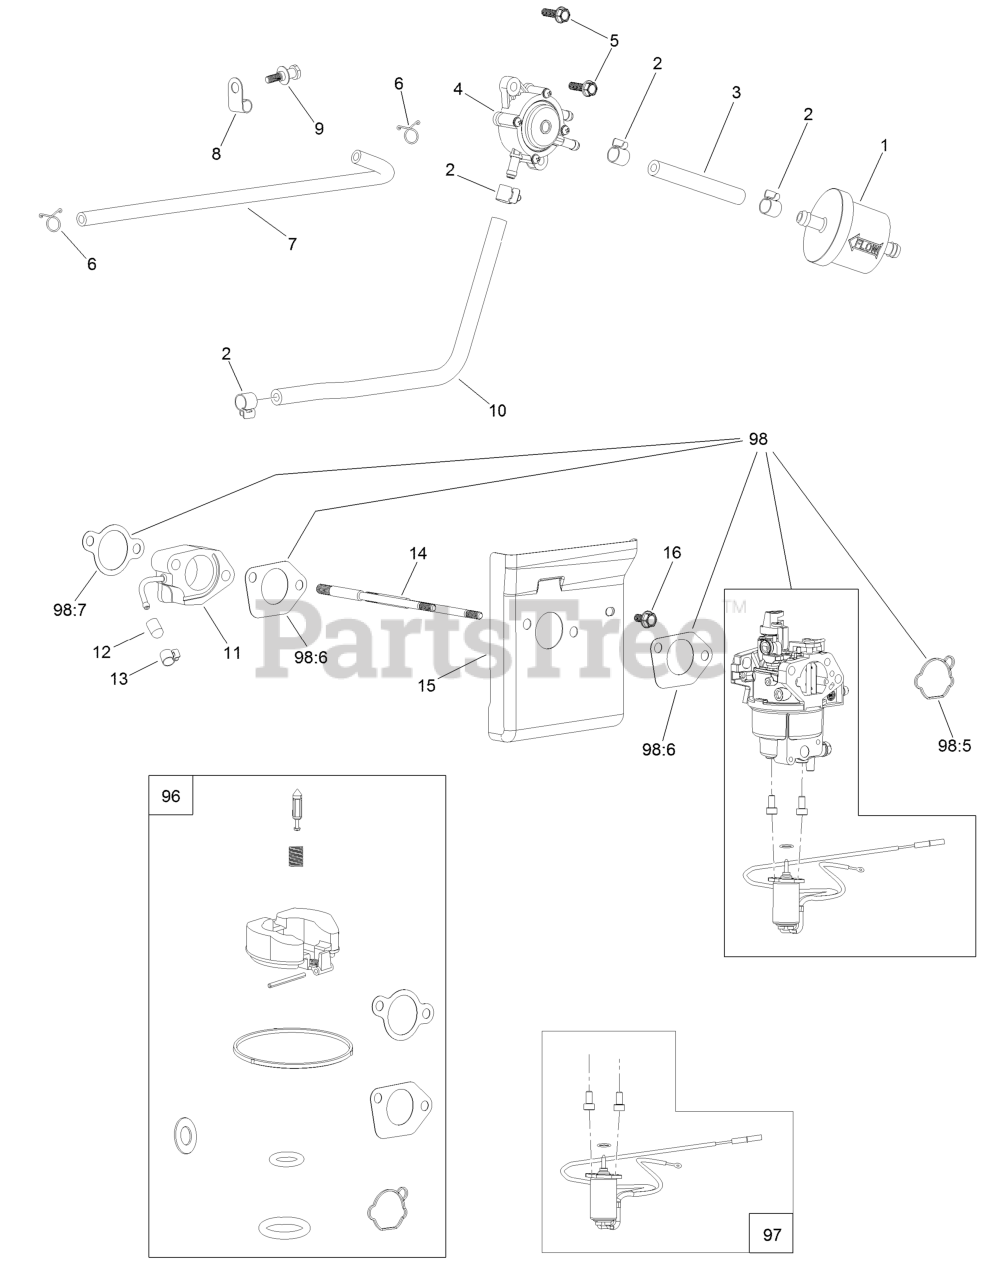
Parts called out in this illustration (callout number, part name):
1	Filter-Fuel
2	Clamp-Fuel Line
3	Line-Fuel
4	Pump-Pulse, Fuel
5	Screw-HHF
6	Clamp-Hose
7	Line-Pulse
8	Clamp-J
9	Screw-Shoulder, HH
10	Line-Fuel
11	Insulator-Carburetor
12	Cap-Seal
13	Clamp-Hose
14	Stud-Mount, Carburetor
16	Screw-HHF
96	Carb Repair Kit With Gaskets
97	Solenoid Kit
98	Carburetor Kit
98:5	Gasket-Carburetor
98:6	Gasket-Carburetor
98:7	Gasket-Carburetor
99	High Altitude Kit
